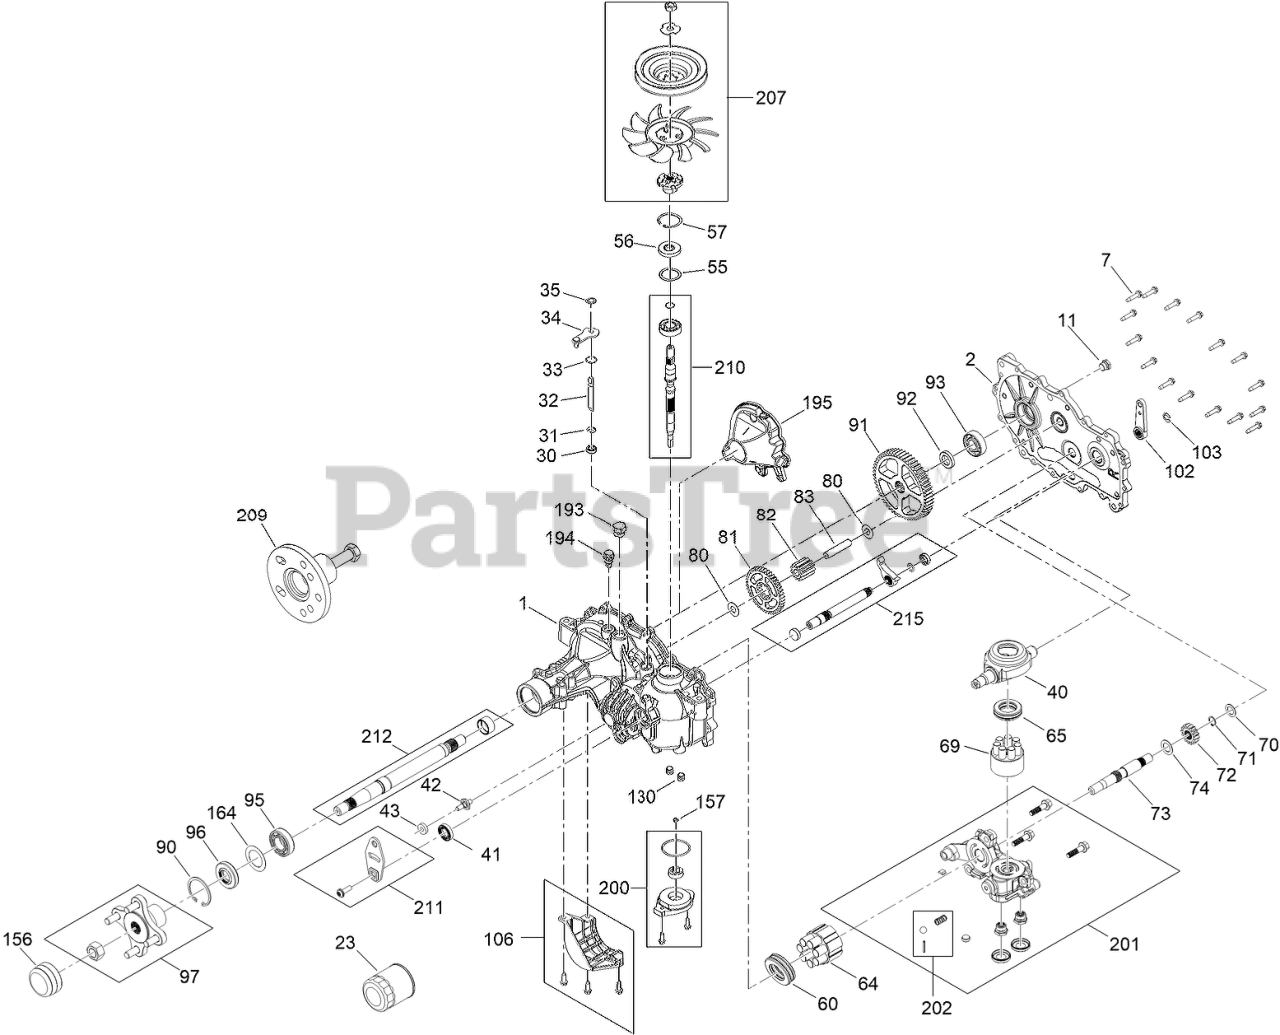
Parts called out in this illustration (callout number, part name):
1	RH MAIN HOUSING KIT
2	RH SIDE COVER KIT
7	SCREW-HHF
23	ELEMENT-OIL FILTER, HYD
30	SEAL-LIP
31	RING-RETAINING, EXTERNAL
32	ROD-BYPASS
33	RING-RETAINING, INTERNAL
35	RING-RETAINING, EXTERNAL
40	SWASHPLATE-TRUNNION
41	SEAL-LIP
43	PUCK-FRICTION
55	SPACER
56	SEAL-LIP
57	RING-RETAINING
60	BEARING-THRUST
64	CYLINDER BLOCK ASM KIT
65	BEARING-THRUST
69	PUMP BLOCK ASM
70	WASHER-FLAT
71	RING-RETAINING
72	GEAR-14T
73	SHAFT-MOTOR
74	WASHER
80	WASHER
81	GEAR-45T
82	GEAR-11T
83	PIN-JACKSHAFT
90	RING-RETAINING
91	GEAR-54T
92	SPACER
93	BEARING-BALL
95	BEARING-BALL
97	HUB KIT
102	HANDLE-BRAKE
103	RING-RETAINING, EXT
106	FILTER GUARD KIT
130	TUBE-CHARGE
156	COVER-NUT, AXLE
157	GEROTOR SEAL KIT
164	SPACER
194	BREATHER FITTING ASM
195	RH INTERNAL EXPANSION TANK ASM
200	SEAL KIT
201	KIT, CENTER SECTION, LH CHARGE
202	CHARGE RELIEF KIT
207	FAN AND PULLEY KIT
210	INPUT SHAFT KIT
211	CONTROL ARM KIT
212	AXLE SHAFT KIT
215	INBOARD KIT
